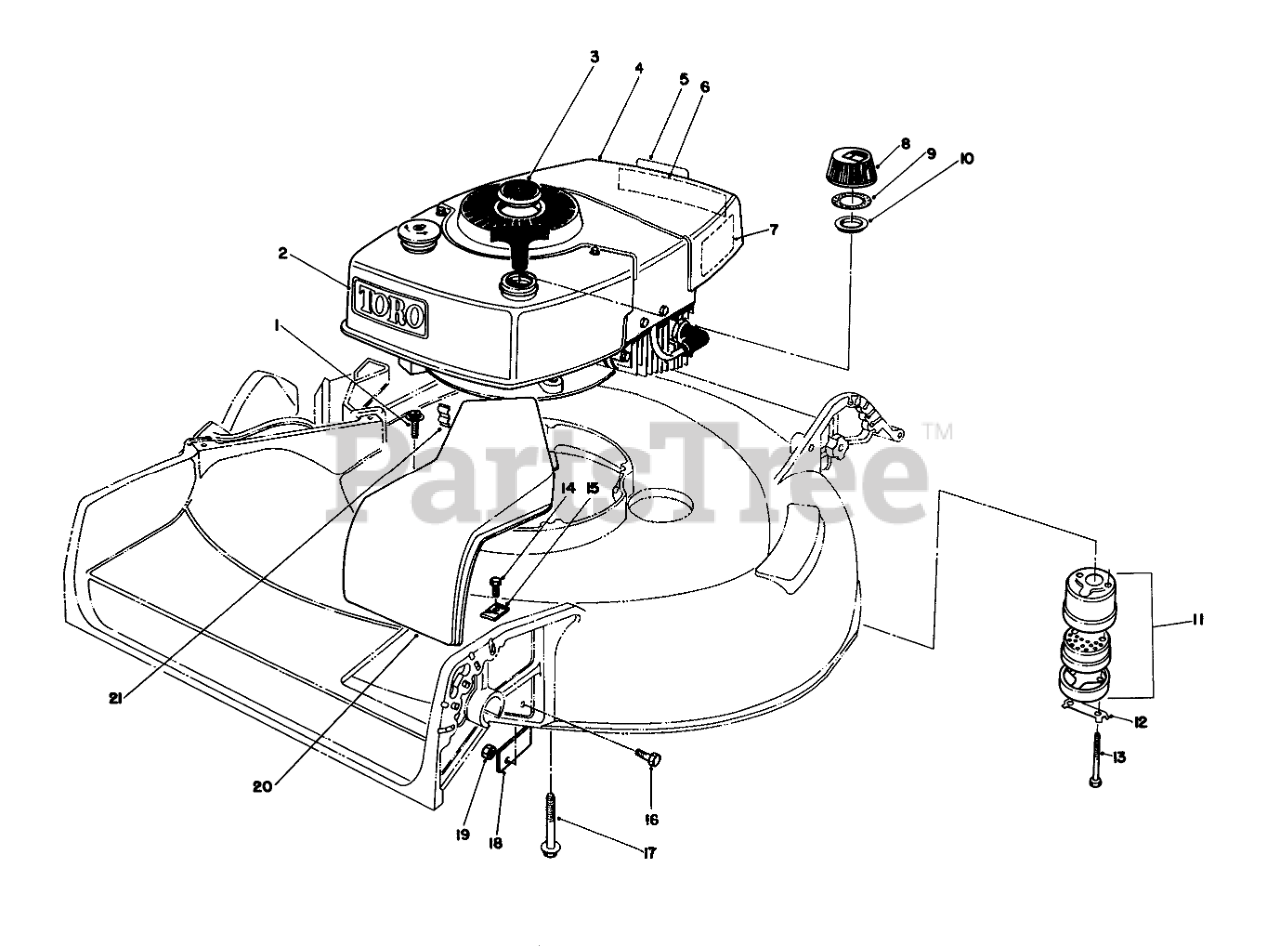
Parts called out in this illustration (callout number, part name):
1	SCREW
2	Decal Tow
3	Plug Button
5	DECAL-PRIMER
6	Decal Maintenance
7	Decal-Maintenance
8	Gas Cap Assembly (Incl. Ref. #9 & 10)
9	GASKET
10	GAS CAP BAFFLE
11	Muffler (Incl. Ref. #13 & 14)
12	CLIP - LOCKING
13	SCREW-HH
14	SCREW-HWHTF
15	Cable Clamp
16	SCREW-HH
17	3/8-16 X 2-3/4 CAPSCR
18	Shield Front
19	NUT-LOCK, NI
20	Cow-Belt
21	Clip Conduit
